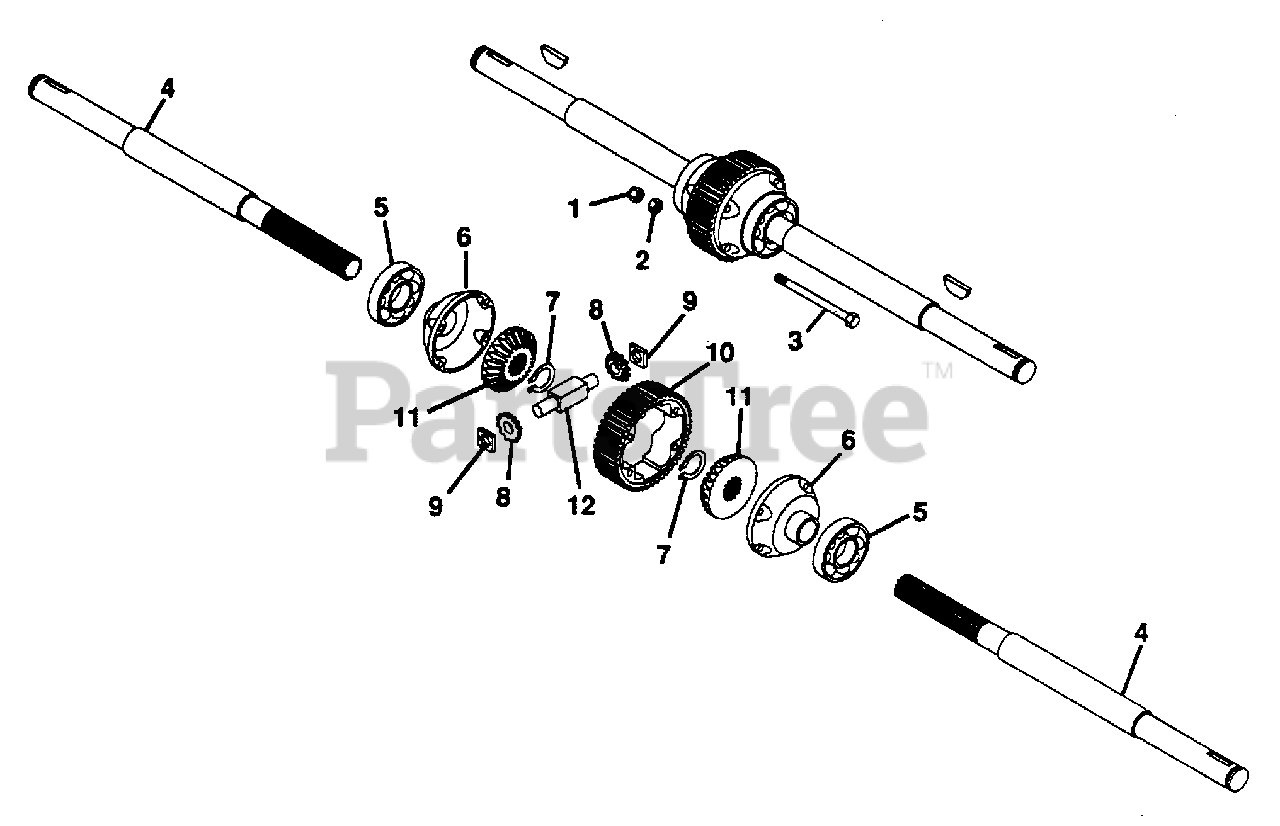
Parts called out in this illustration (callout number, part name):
1	NUT, LOCK 5/16-18
2	NUT, HEX 5/16-18 GRADE-8
3	BOLT, HEX 5/16-18X2.75 GRADE-8
4	AXLE, BEVEL GEAR DIFFERENTIAL
5	BEARING, BALL
6	CAP, DIFFERENTIAL END
7	RING, RETAINING 1.250 SFT HEAVY
8	PINION, BEVEL
9	BLOCK, DRIVE
10	GEAR, FINAL DRIVE
11	GEAR, BEVEL
12	PIN, SPIDER PINION
